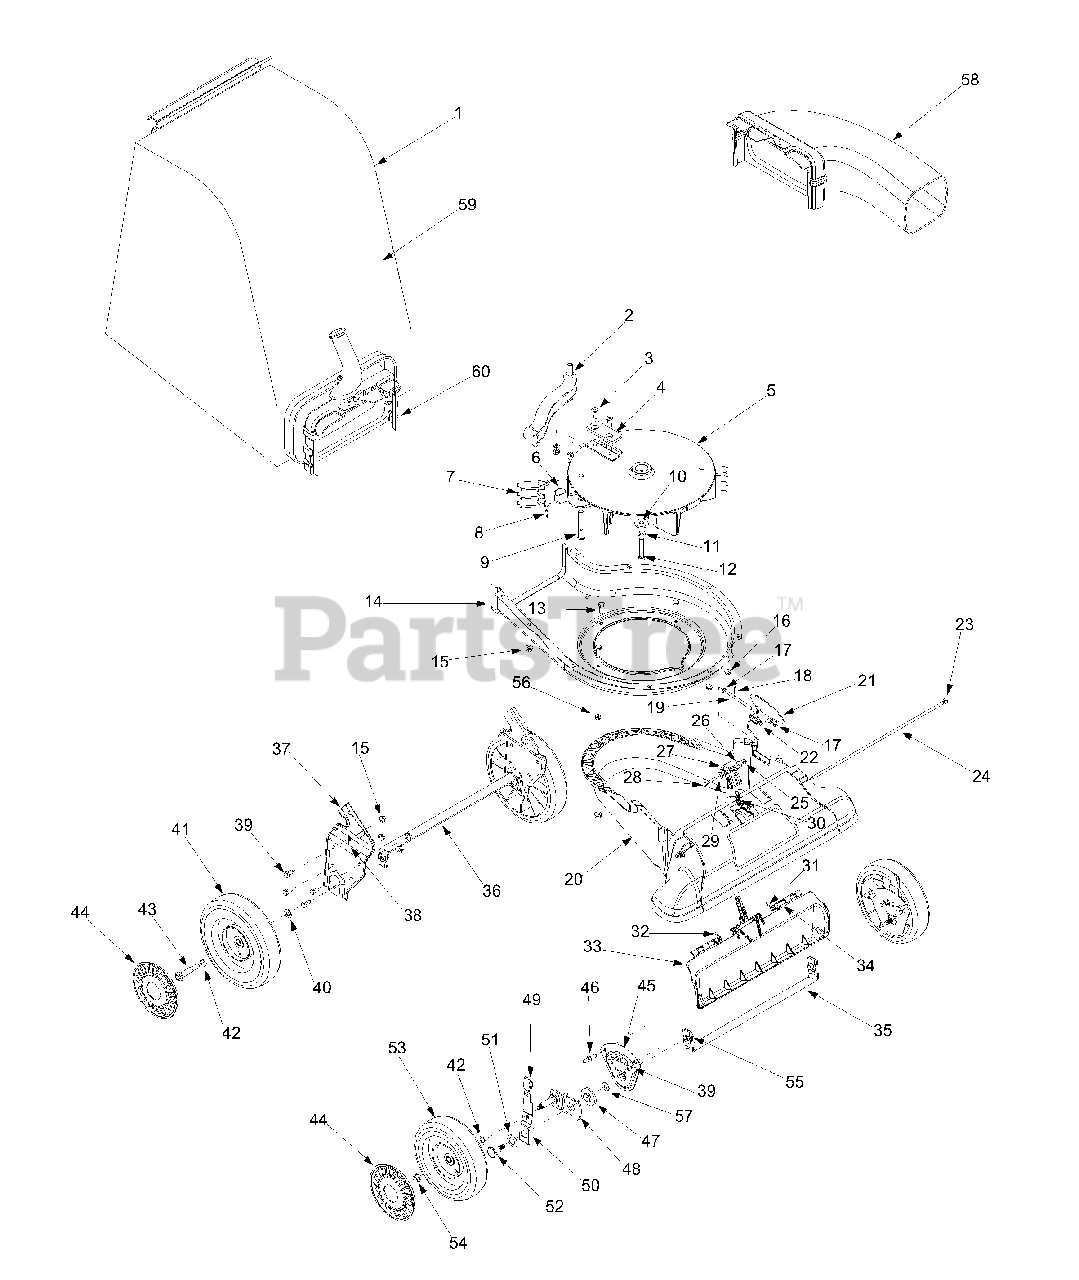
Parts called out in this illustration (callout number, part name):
1	Bag Assembly
3	Hex Screw 5/16-24 x 1.0
4	Chipper Blade
5	Impeller Assembly
7	Flail Blade
8	Spiral Pin
9	Clevis Pin
10	Flat Washer.375 ID x 1.25 OD
11	Lock Washer 3/8
12	Hex Cap Screw 3/8-24 x 2.0
13	Hex Cap Screw 5/16-18 x .875
15	Flange Lock Nut 5/16-18
16	Hex Flange Nut 1/4-20
17	Flat Washer .281 ID x .50 OD
18	Cotter Pin
19	Pivot Rod
20	Nozzle
21	Base Adapter Door
22	Torsion Spring
23	Cap Speed Nut 1/4
24	Pivot Rod
25	Hex Lock Nut #10-24
26	Flat Washer .194 ID x .62 OD
27	Nozzle Door Lever
28	Hex Screw #10-24 x 1.25
29	Shoulder Spacer
30	Extension Spring
31	Torsion Spring LH
32	Torsion Spring RH
33	Nozzle Door
34	Rod .25 x 1.25 Lg
38	Cotter Pin
39	Hex Cap Screw 5/16-18 x.625
40	Bell Washer.401 ID x.870 OD
41	Wheel 9 x 2
42	Wave Washer .531 ID x .781 OD
43	Shoulder Screw 3/8-16
44	Hubcap
47	Height Adjustment Bearing
48	Pivot Arm Assembly
49	Height Adjustment Knob
50	Spring Lever
51	Bell Washer .760 ID x .25 OD
52	Shoulder Screw .750 ID x .625 OD
53	Wheel 8 x 2
54	Flange Lock Nut 3/8-16
55	Lock Nut 3/8-16
56	Hex Lock Nut 5/16-18
57	Thrust Washer .375 ID x .70 OD
58	Blower Chute (If Equipped)
59	Bag
60	Chute Assembly
